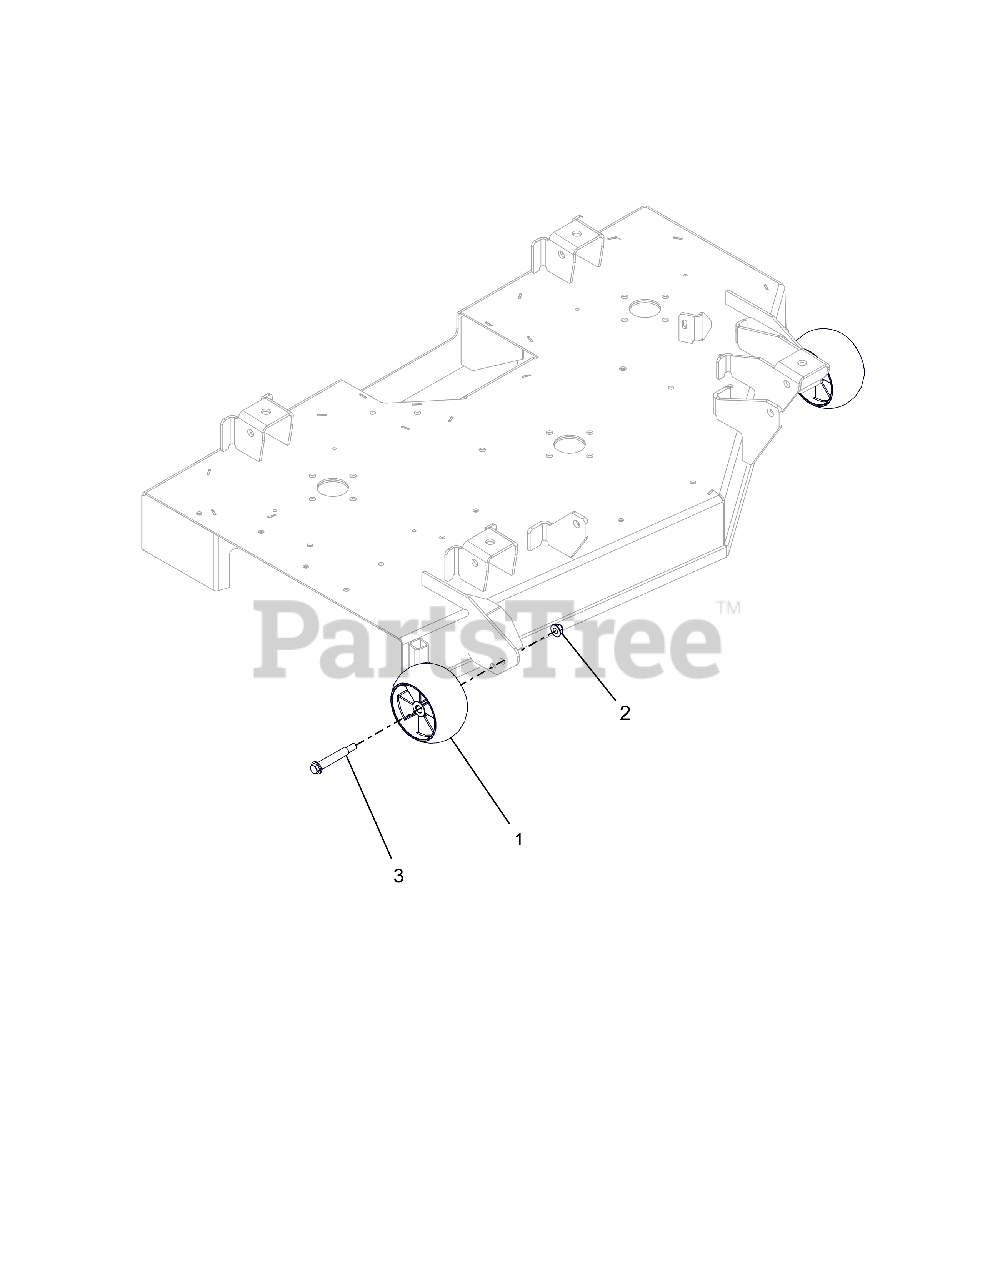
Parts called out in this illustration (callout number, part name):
1	ANTI-SCALP WHEEL - 5X OS
2	NUT,NYL-FLG .38-16 GF ZCC
3	BLT-SHLDR .38-16X2.50 HWH G5
